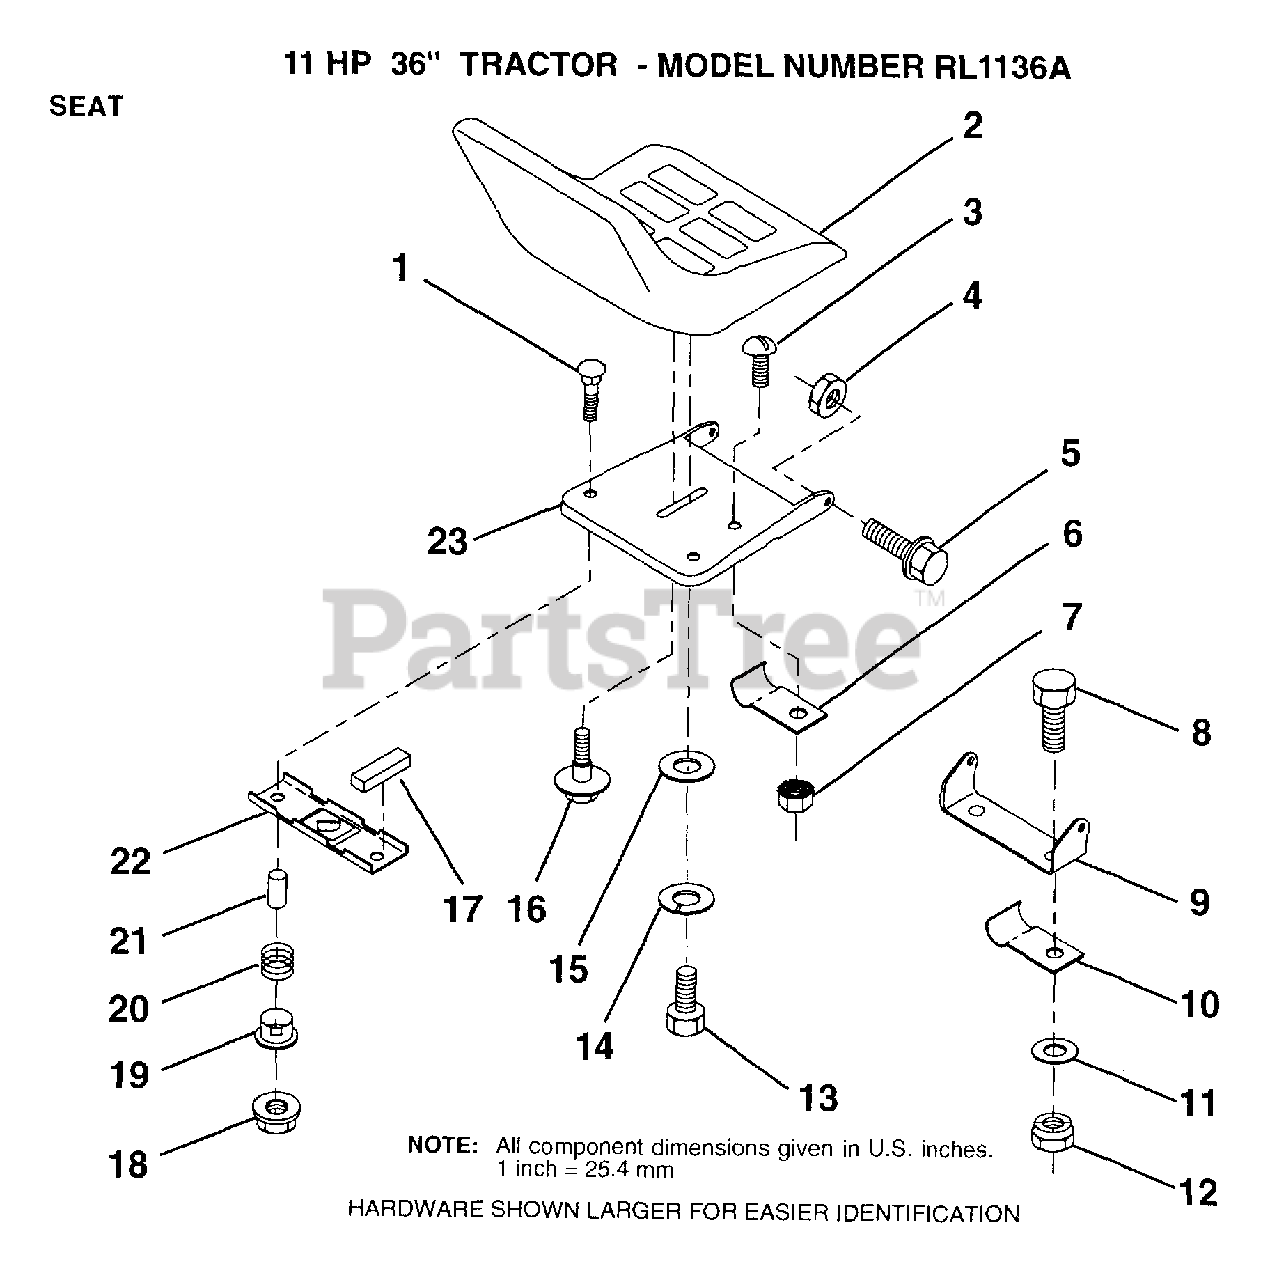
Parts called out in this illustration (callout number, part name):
7	"NUT,KEPS"
10	"CLIP,INSULATOR"
11	WASHER
13	BOLT
14	LOCKWASHER
15	WASHER
16	"BOLT,SHOULDER"
17	STRIP FORM
19	BUSHING
20	SPRING
21	SPLIT SPACER
22	BRKT SWITCH
